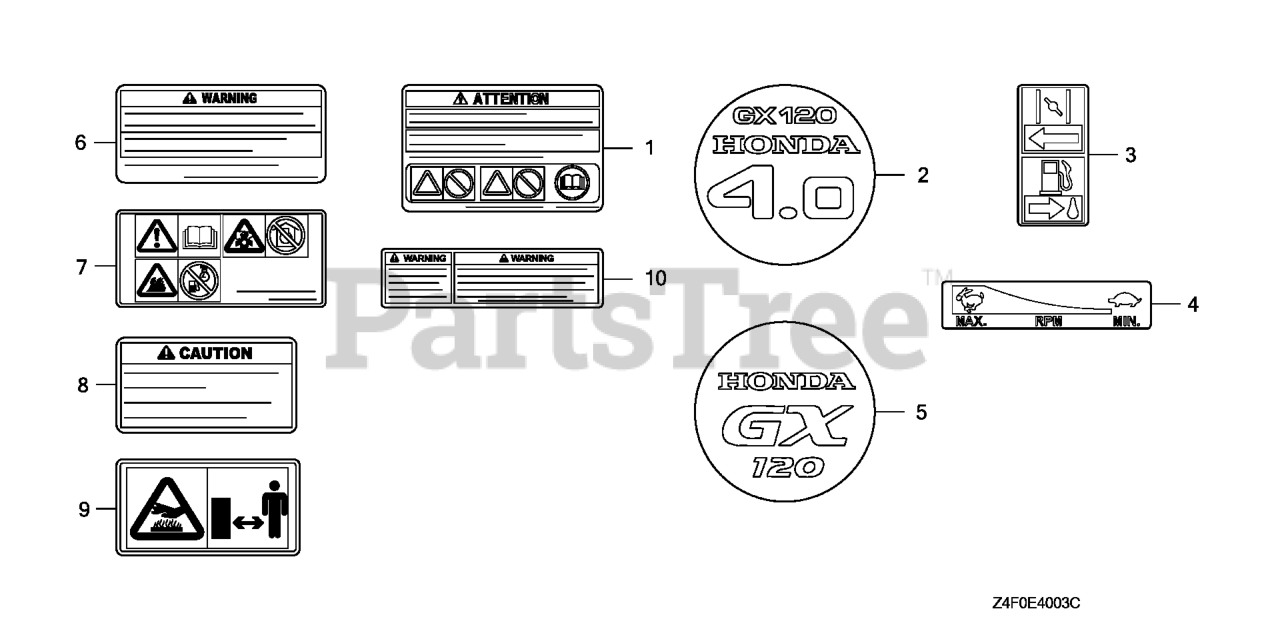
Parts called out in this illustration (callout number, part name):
1	MARK, OPERATOR CAUTION (FRENCH)(MADE IN JAPAN)
6	MARK, OPERATOR CAUTION (FRENCH)(MADE IN JAPAN)
7	MARK, OPERATOR CAUTION (PICTOGRAPH)
8	MARK, EX. CAUTION (FRENCH)
9	MARK, EX. CAUTION (PICTOGRAPH)
